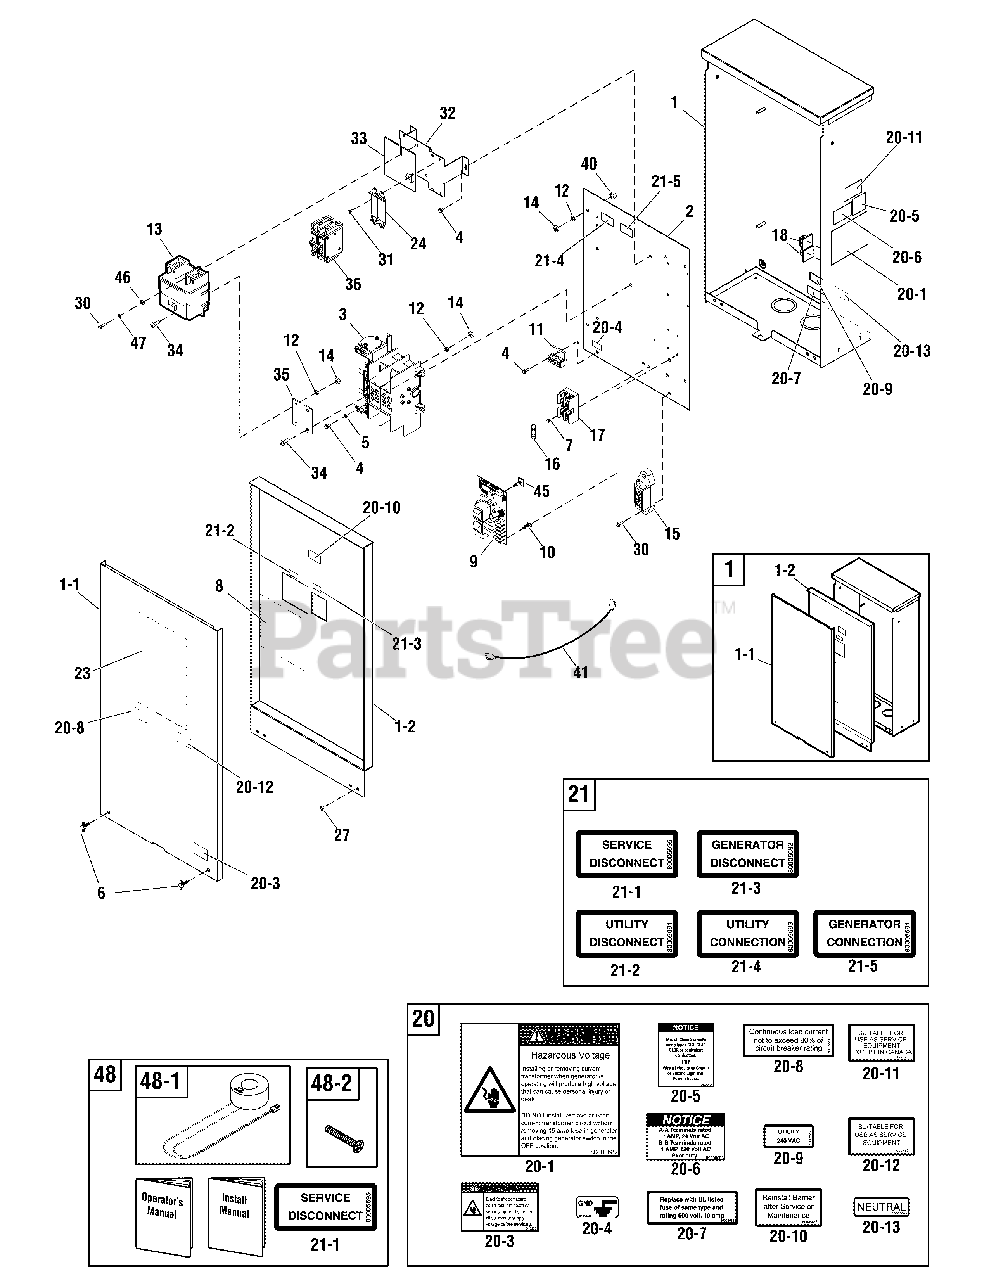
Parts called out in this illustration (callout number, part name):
1	ENCLOSURE
2	BACK PANEL
3	SWITCH, Transfer
4	* TRILOBULAR, #10-32 x 1/2
5	* WASHER, External Tooth, #10
7	* SCREW, Hex Head, Trilobular, #6-32 x 3/8
9	BOARD, Circuit
11	LUG
12	* WASHER, Lock, 1/4
13	BREAKER, Circuit, 150A
14	* NUT, 1/4-20
20	DECAL SHEET - WARNINGS
20-1	DECAL, Warning Voltage
20-3	DECAL, Warning Shock
20-4	DECAL, Ground
20-5	DECAL, Notice
20-6	DECAL, Contacts Rated
20-7	DECAL, Fuse, 10 Amp
20-8	DECAL, Breaker, Circuit
20-9	DECAL, Sensing, Utility
20-10	DECAL, Reinstall After
20-11	DECAL, Not Suitable
20-12	DECAL, Suit. as Service Equip.
20-13	DECAL, Neutral
21	DECAL SHEET-CONNECTIONS
21-1	DECAL, Service Disconnect
21-2	DECAL, Disconnect Utility
21-3	DECAL, Gen Disconnect
21-4	DECAL, Connection, Utility
21-5	DECAL, Connect Gen
27	TRILOBULAR, #10-32 x 3/8"
30	* SCREW, Hex Head, Trilobular, #10-32 x 3/4
31	* TRILOBULAR, 8-32 x 3/8
34	* SCREW, Phillips Head, 1/4-20x 3/4
35	BAR, Bus
36	BREAKER, Circuit, 100A
40	SPACER
46	* WASHER, Flat, #10
47	* WASHER, Lock, #10
48	KIT, Manual/ACC
48-1	CURRENT TRANSFORMER
